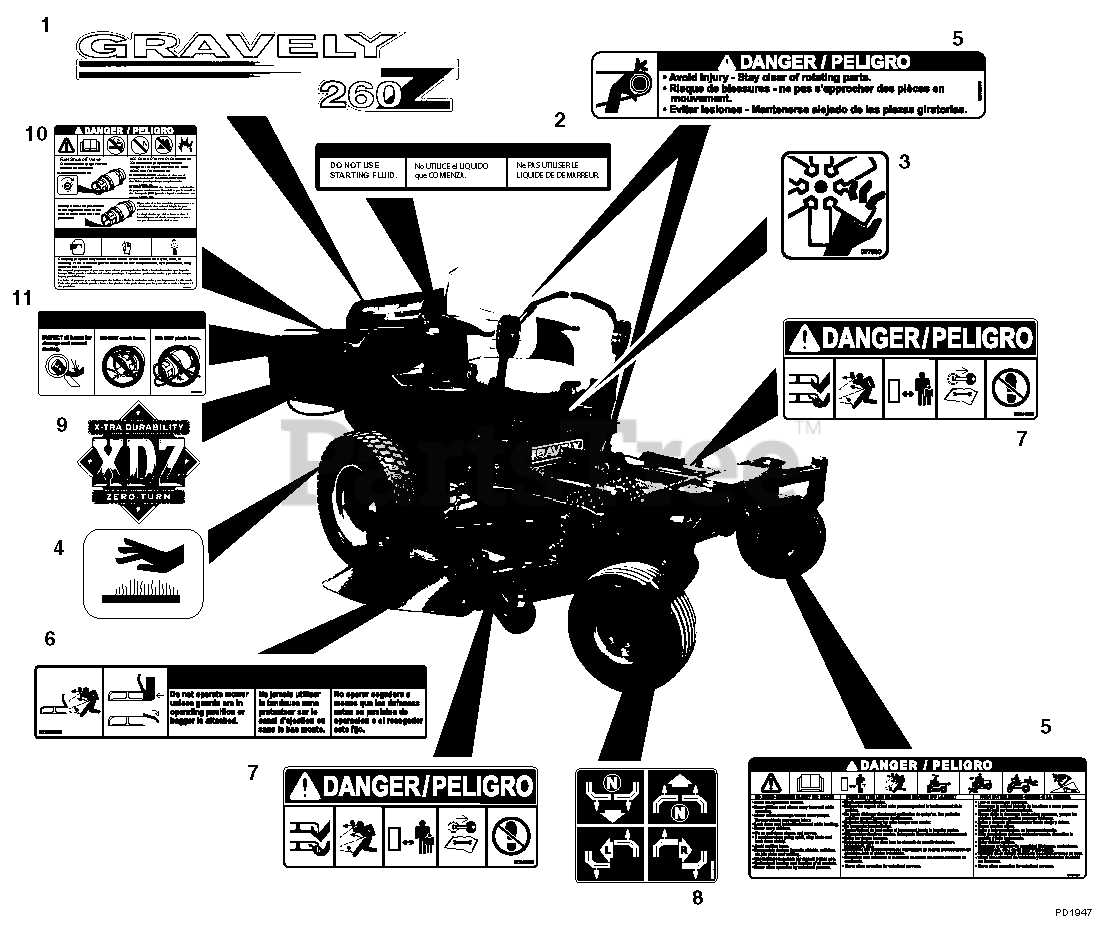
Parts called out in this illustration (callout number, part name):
1	Decal, PM-260Z Hood
2	Decal, No Starting Fluid
3	Decal, Danger Fan
4	Decal-Hot Surface
5	Set, Decal-Common Danger/Fuel
6	Decal, Warning
7	Decal, Mower Pan Head Danger
8	Decal-Instructional
9	Decal, XDZ
10	Decal, Tank Specification
11	Decal, Hose Inspection
